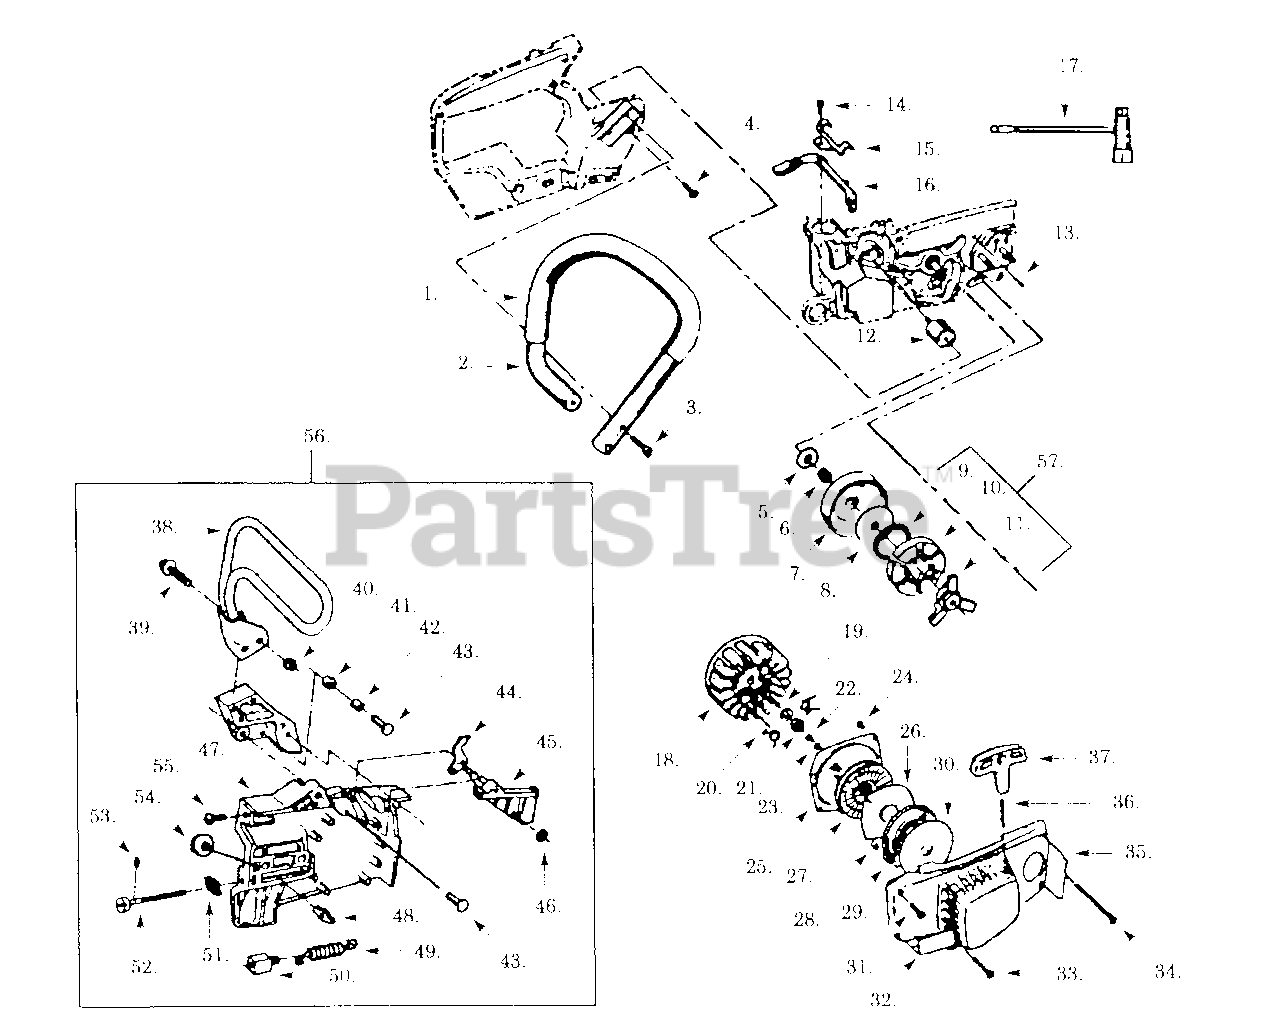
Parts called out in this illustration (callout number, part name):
1	Handlebar Grip Kit
2	Handlebar Ass'y.
6	Clutch Bearing
7	Drum & Sprocket Ass'y.
8	Clutch Plate
9	Clutch Spring
10	Clutch Shoe
11	Clutch Spider
12	Model 385
12	Model 375,395
13	Oil Vent Replacement Kit
16	Model 375
16	Model 385,395
17	Model 375
17	Model 385,395
18	Flywheel Ass'y.
19	Washer
20	Starter Dog Spring
21	Flywheel Nut
22	Screw
25	Air Baffle
26	Disc Recoil Spring-Inner
27	Starter Pulley
29	Starter Recoil Spring
30	Disc Recoil Spring-Outer
32	Model 375
32	Model 385,395
35	Fan Housing Ass'y.
36	Rope Kit
38	Handguard Ass'y.
40	Nut
41	Latch Roller
42	Bushing Latch
46	Retaining Ring
47	Clamp & Arm Ass'y.
48	Bar Adjusting Pin
49	Extension Spring
54	Nut
56	Chain Brake Kit-Model 385,395
57	Clutch Ass'y. (Inc.9,10,11)
58	Chain Brake Warning Decal
